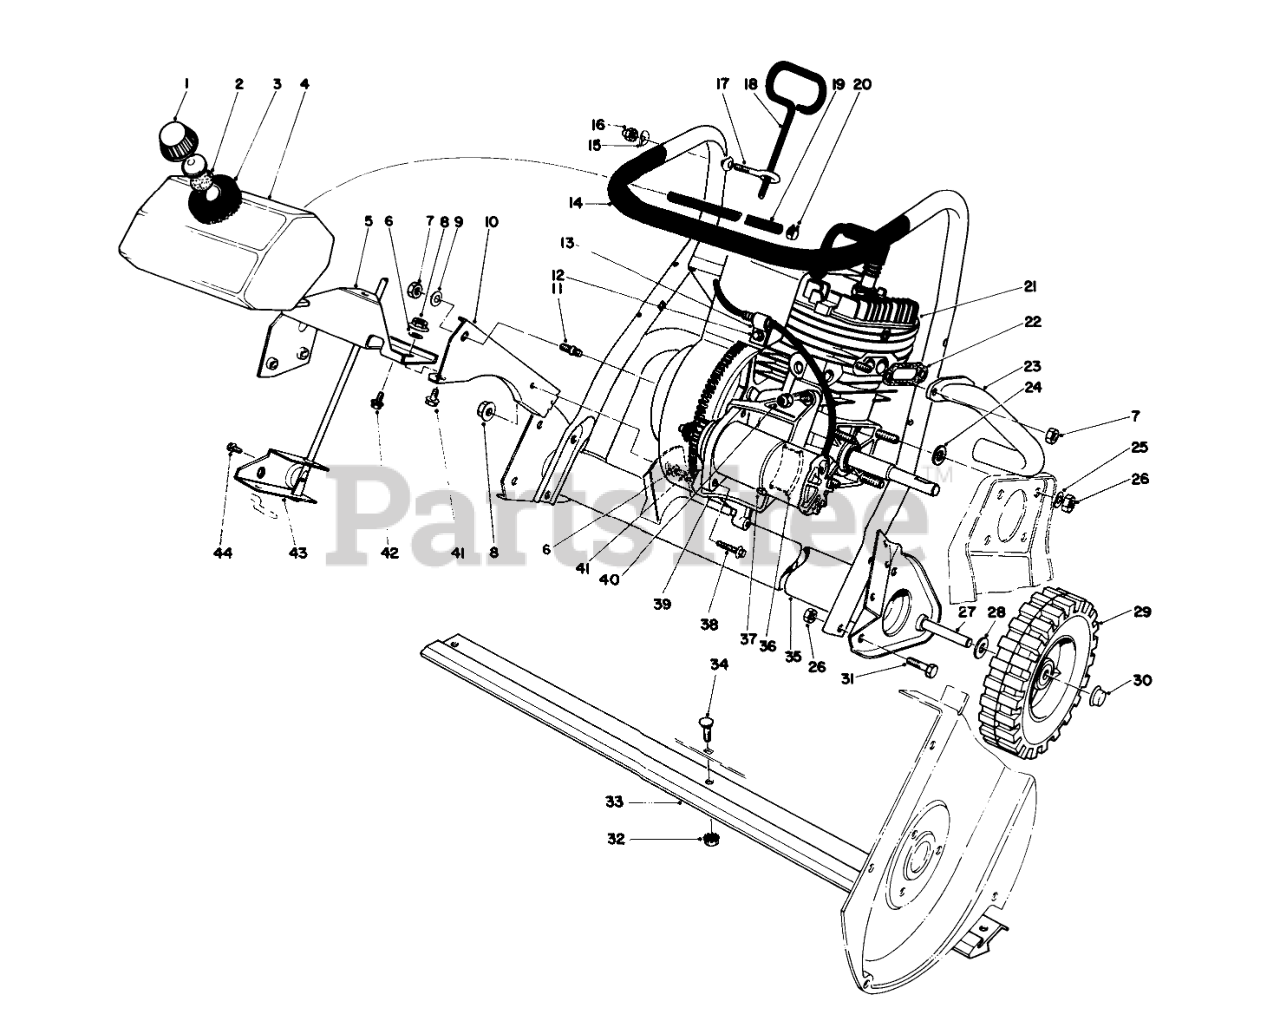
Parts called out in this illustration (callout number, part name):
1	GAS CAP ASM
2	GAS CAP GASKET
3	FOAM PAD
4	GAS TANK
5	Support-Gas Tank
6	WASHER-LOCK
7	NUT-LOCK, CONE
9	GRILLE HINGE SPACER
10	ENGINE SUPPORT
12	SCREW-HWH
13	CABLE CLAMP
14	Lower Handle
15	WASHER
16	NUT-CAP
17	EYEBOLT
18	ADJ ROD ASM
19	GasLine
20	Clamp
21	Engine
22	EXHAUST GASKET
23	EXHAUST PIPE
24	WASHER-FLAT
25	WASHER-PLAIN
26	NUT-LOCK, NI
28	WASHER-FLAT
29	WHEEL
30	RETAINER-PUSH ON
31	SCREW-HH
32	NUT-KEPS
33	SCRAPER
34	BUTTON HD CARR SCR
35	MUFFLER ASSEMBLY
36	RR MOTOR SUPPORT
37	TIE-CABLE
38	SCREW-FLOW, TAPTITE
39	MOTOR MTG BRKT
40	NUT-LOCK, NI
41	5/16-18X.62 WHIZLOK SCR
42	SCREW-HWH
43	VANE ADJ BRKT
44	SCREW
